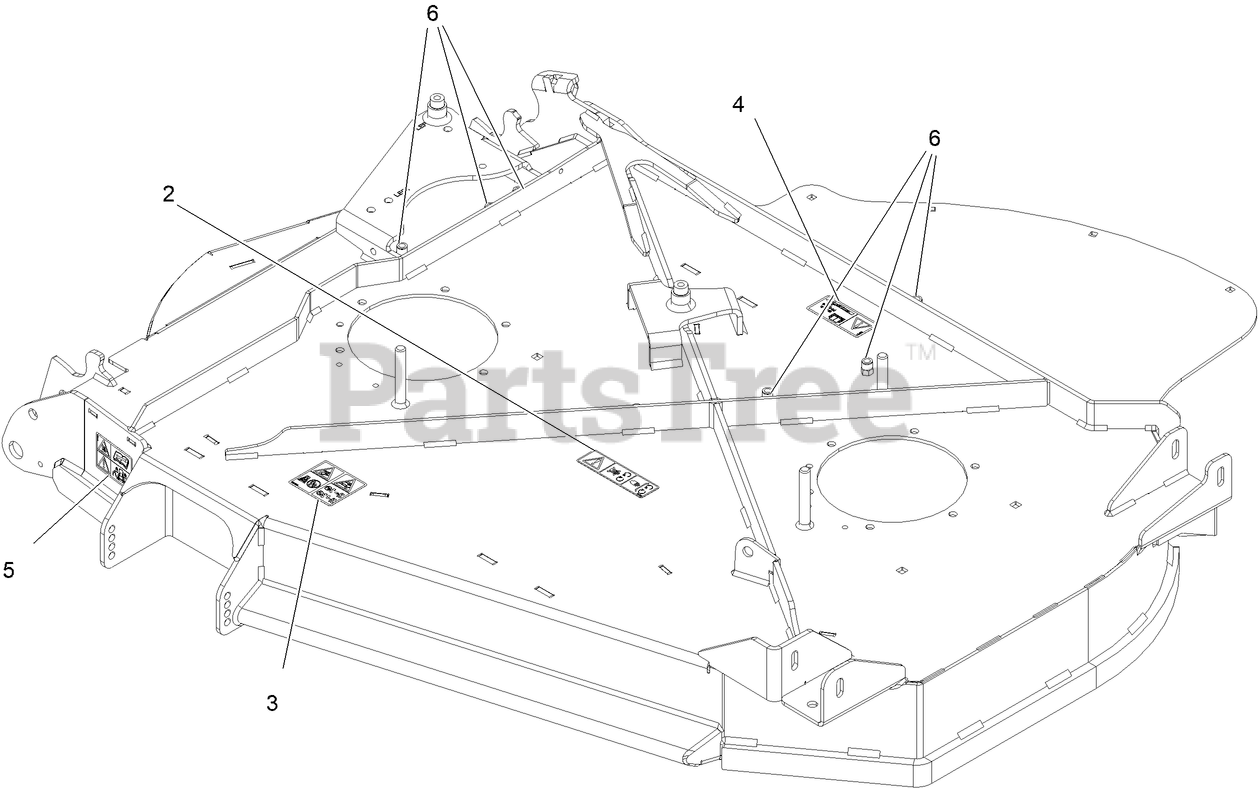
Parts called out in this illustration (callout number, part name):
2	DECAL-COVER, MISSING
3	DECAL-DANGER, THROWN OBJECT
4	DECAL-TORQUE, BOLT
5	DECAL-WARNING, PINCH POIN
6	NUT-CLINCH,HEX
